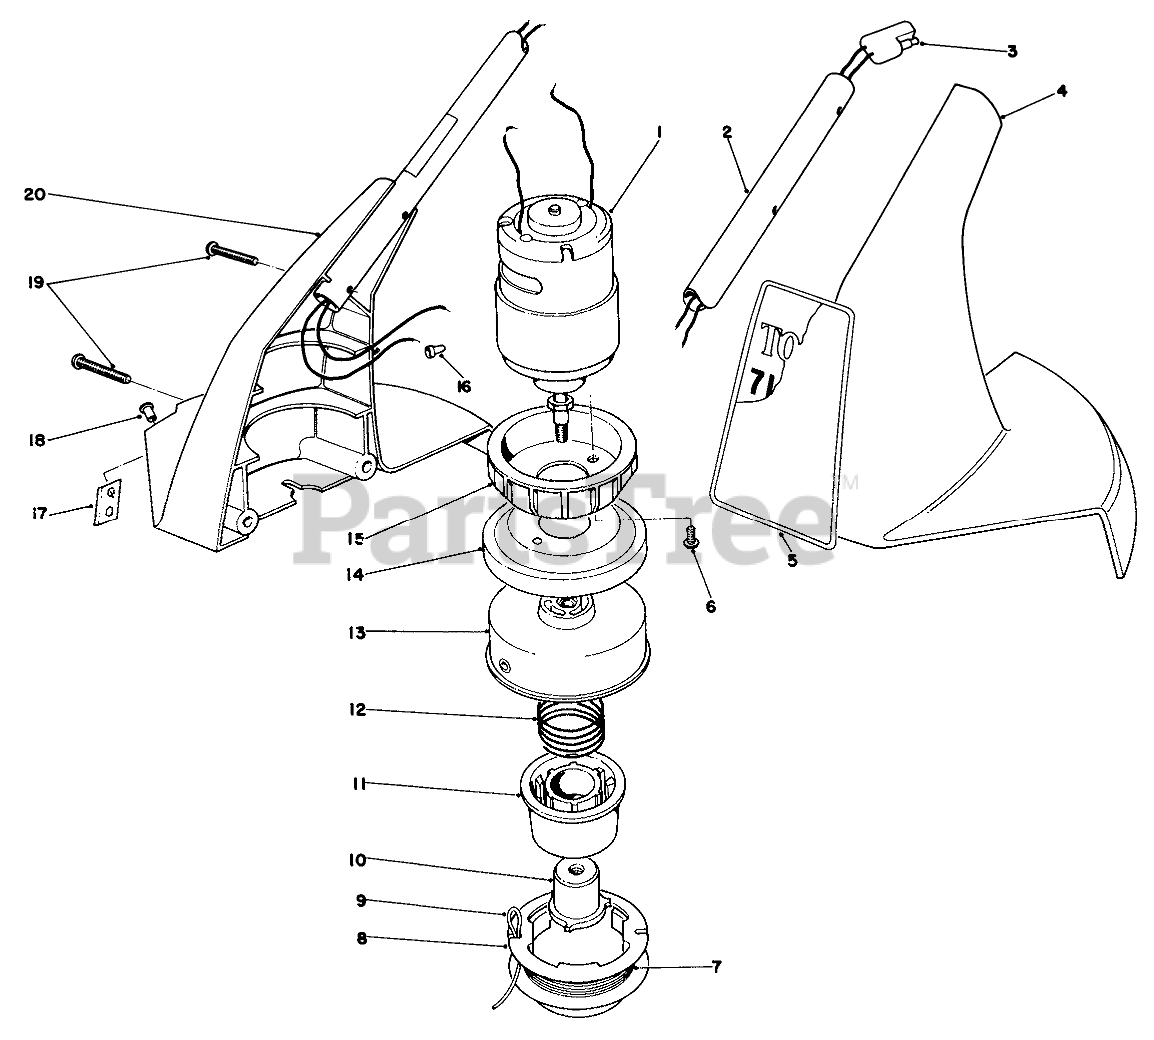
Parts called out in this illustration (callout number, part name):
1	MOTOR ASM
2	EXTENSION HANDLE
3	WIRING HARNESS LOWER
4	Housing-L.H.
5	710 HOUSING DECAL
6	SCREW
7	Cutting Line (12- .05 Dia.)
8	CAP-SPOOL
9	Cutting Line (30- .05 Dia.)
10	DRIVER
11	CORE - SPOOL
12	Spring
13	Drum w/Eyelet
14	DRUM CUP
15	Casting-Heat Sink
16	Connector
17	Blade-Knife
18	Rivet
19	SCREW-PLASTITE
20	Housing-Motor R.H. (Incl. Ref. #17 & 18)
